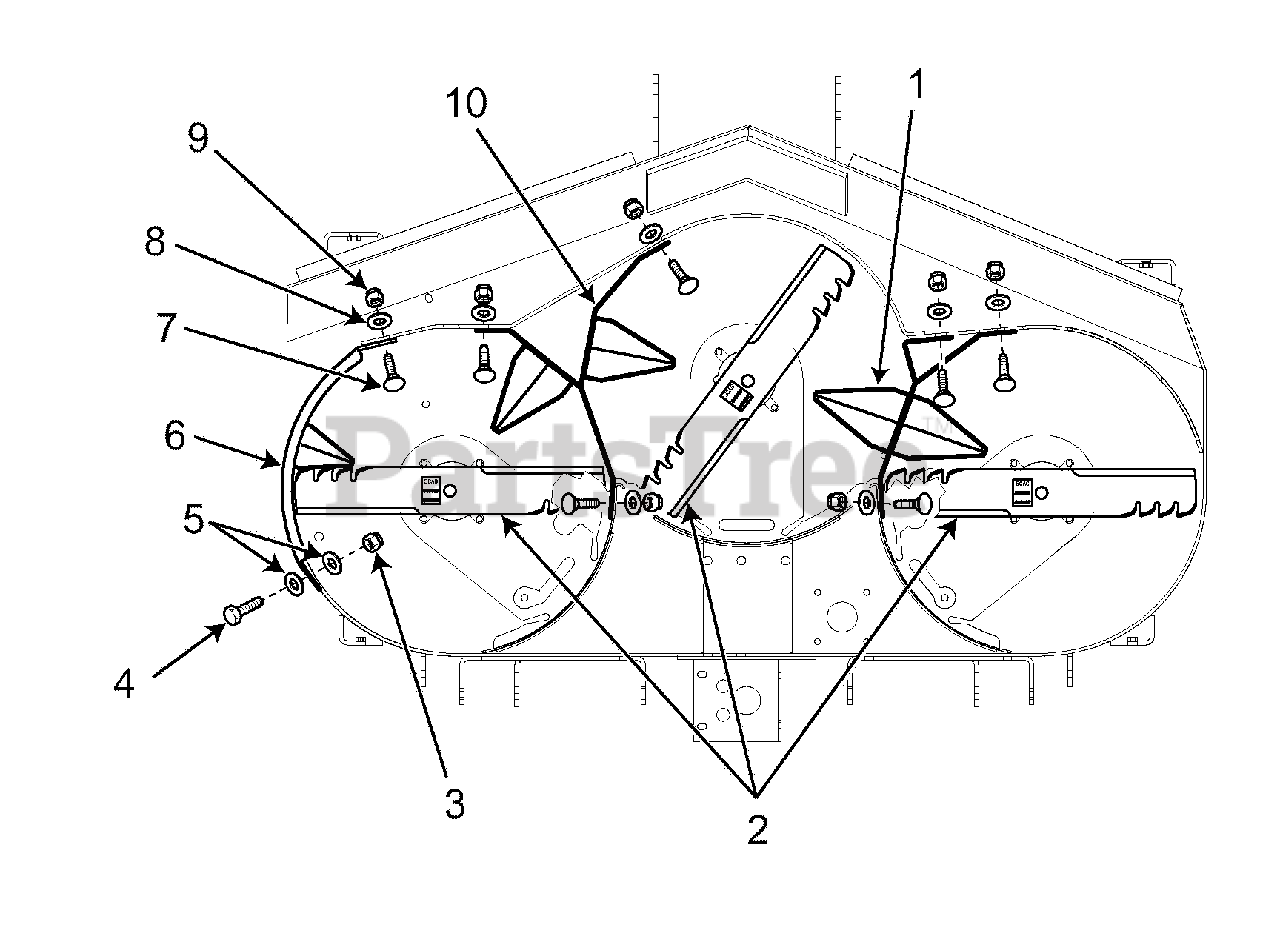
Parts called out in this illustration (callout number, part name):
1	Mulch Baffle L.H.
2	Mulch Blades
3	Elastic Stop Nut 5/16-18
4	H.H. Bolt 5/16-18 x 1"
5	Flatwasher 5/16"
6	Mulch Plate
7	Carriage Bolt 3/8-16 x 1"
8	Flatwasher 3/8
9	Elastic Stop Nut 3/8-16
10	Mulch Baffle R.H.
